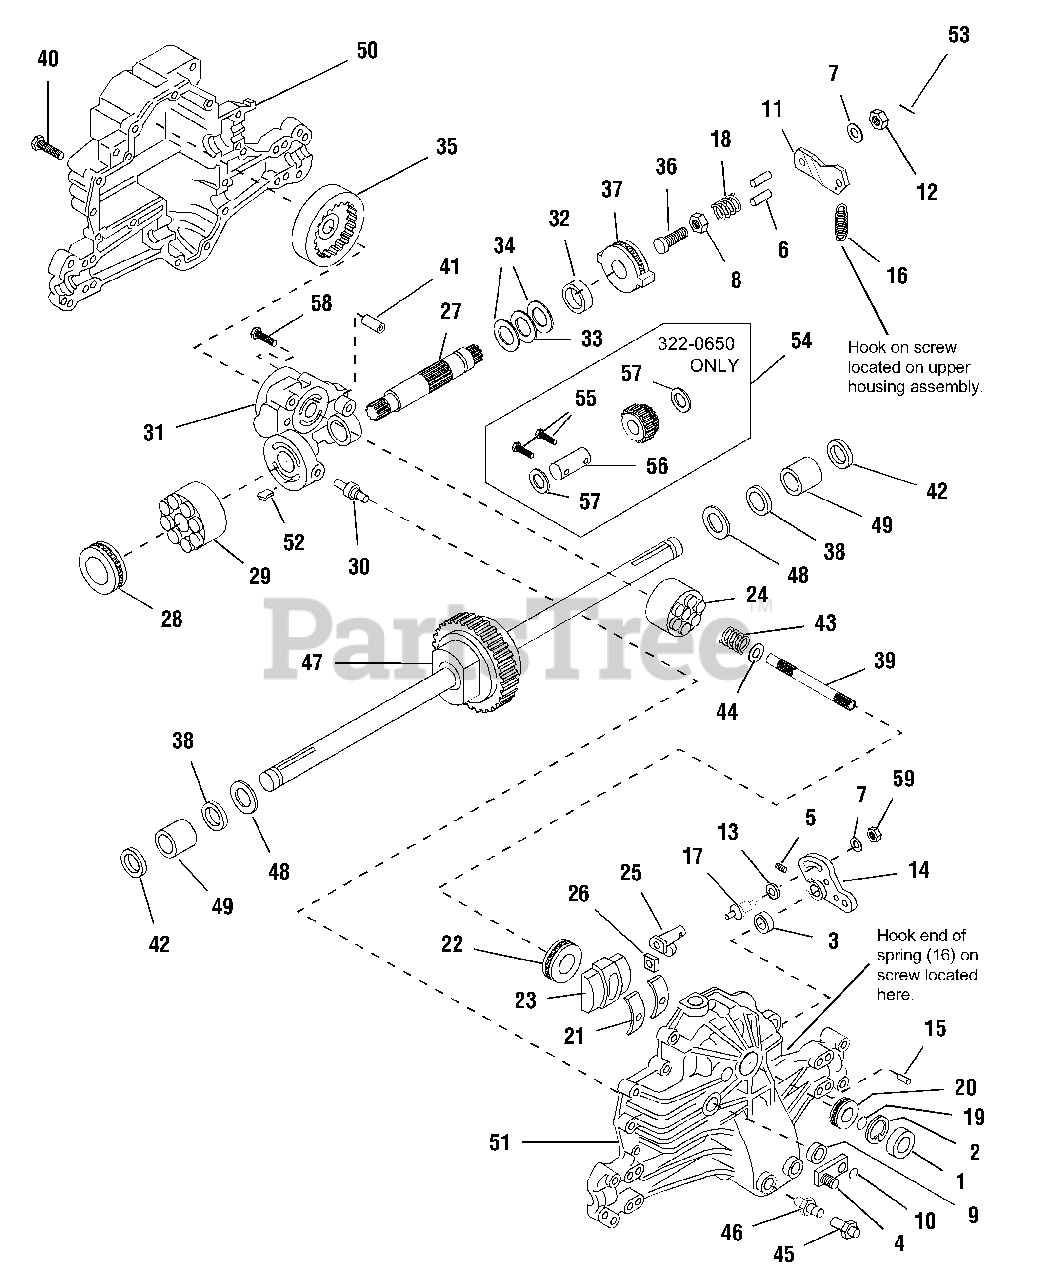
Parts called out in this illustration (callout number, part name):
2	RING, Retaining
6	PIN-ACTUATING
7	WASHER, 7/16 x 7/8 x .060
8	NUT, Hex, Lock, 5/16-24
8	NUT, HEX 5/16-24
9	SEAL-LIP 1.0 x .25 x .7
10	RING, Retaining
11	ARM, Actuating
12	CASTLE NUT, 5/16-24
13	PUCK, Dampener
14	ARM, Control
16	EXTENSION SPRING
17	STUD, 5/16-24
18	COMPRESSION SPRING
19	RING-WIRE, Retaining
20	BEARING, Shaft Ball
21	BEARING, Cradle
22	BEARING, Thrust .30 x .52 x .13
23	SWASHPLATE, Variable
24	BLOCK-CYLINDER PUMP ASSY.
25	ARM, Trunnion
27	SHAFT, Motor
28	BEARING, Thrust .42 x .68 x .16
29	BLOCK-CYLINDER (MOTOR) ASSY.
30	ACTUATOR-BYPASS
31	CENTER SECTION ASSEMBLY
32	SEAL-LIP .26 x .42 x .8
33	RING, Retaining
35	OIL FILTER ELEMENT
36	BOLT, 5/16-18 x 1-3/4
37	BRAKE ROTOR/STATOR KIT
38	SEAL 3/4 x 1-1/4 x 1/4
39	SHAFT, Input
40	BOLT, 1/4-20 x 1-3/8
42	SEAL, Wiper
43	SPRING, Block
44	WASHER, Block Thrust
45	CAP-VENT ASSEMBLY
46	FITTING-O RING ASSEMBLY
47	DIFFERENTIAL ASSEMBLY
48	WASHER-3/4 x 1.5 x .13
49	SLEEVE BEARING
50	HOUSING, Lower
51	UPPER HOUSING ASSEMBLY
52	BYPASS PLATE
53	COTTER PIN
54	JACK SHAFT/PINION GEAR ASSEMBLY
55	CAPSCREW 6M x 20 LG
56	JACK SHAFT
57	WASHER 7/16 x 1 x .5
58	BOLT, 3/8-24 x 2.5
59	NUT-HEX LOCK 5/16-24
